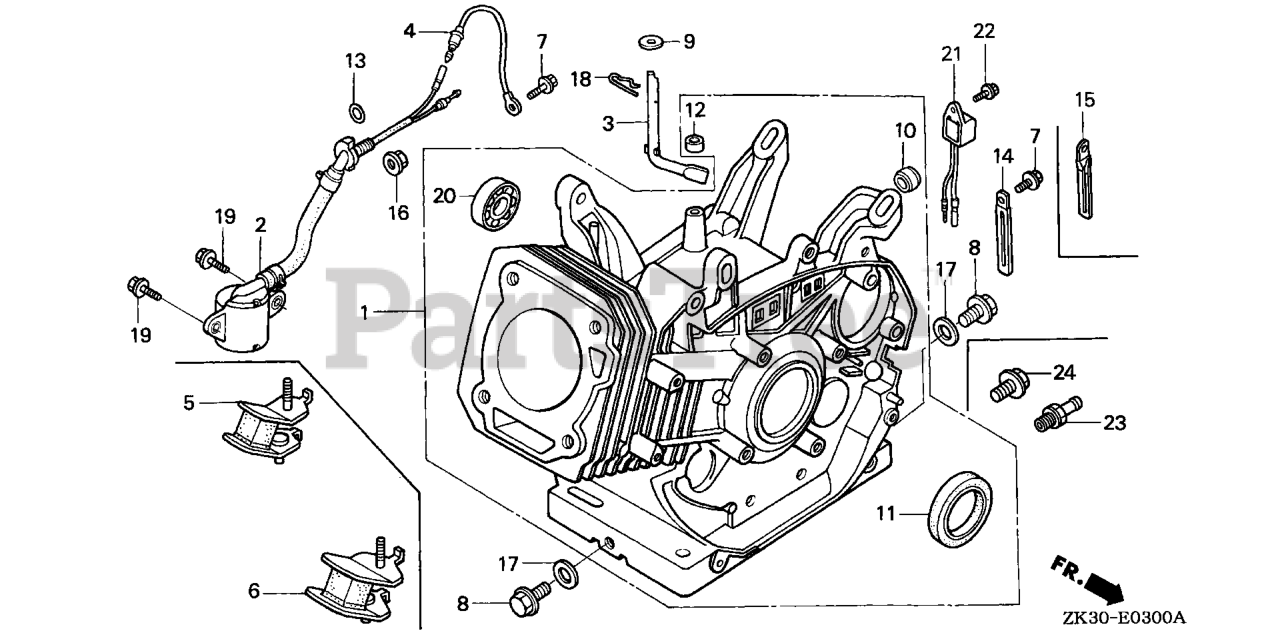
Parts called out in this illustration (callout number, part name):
1	CYLINDER ASSY.
2	SWITCH ASSY., OIL LEVEL
3	SHAFT, GOVERNOR ARM
4	SUB-HARNESS (NOT AVAILABLE)
7	BOLT, FLANGE (6X12) (CT200)
8	BOLT, DRAIN PLUG
9	WASHER (8.2X17X0.8)
10	PLUG, SEALING
11	OIL SEAL (35X52X8)
12	OIL SEAL (8X14X5)
13	O-RING (14MM) (ARAI) Use up to Engine SN 2949254.
16	NUT, FLANGE (10MM)
17	WASHER, DRAIN PLUG (12MM)
18	PIN, LOCK (10MM)
19	BOLT, FLANGE (6X12) Use up to Engine SN 1543277.
20	BEARING, RADIAL BALL (6202)
